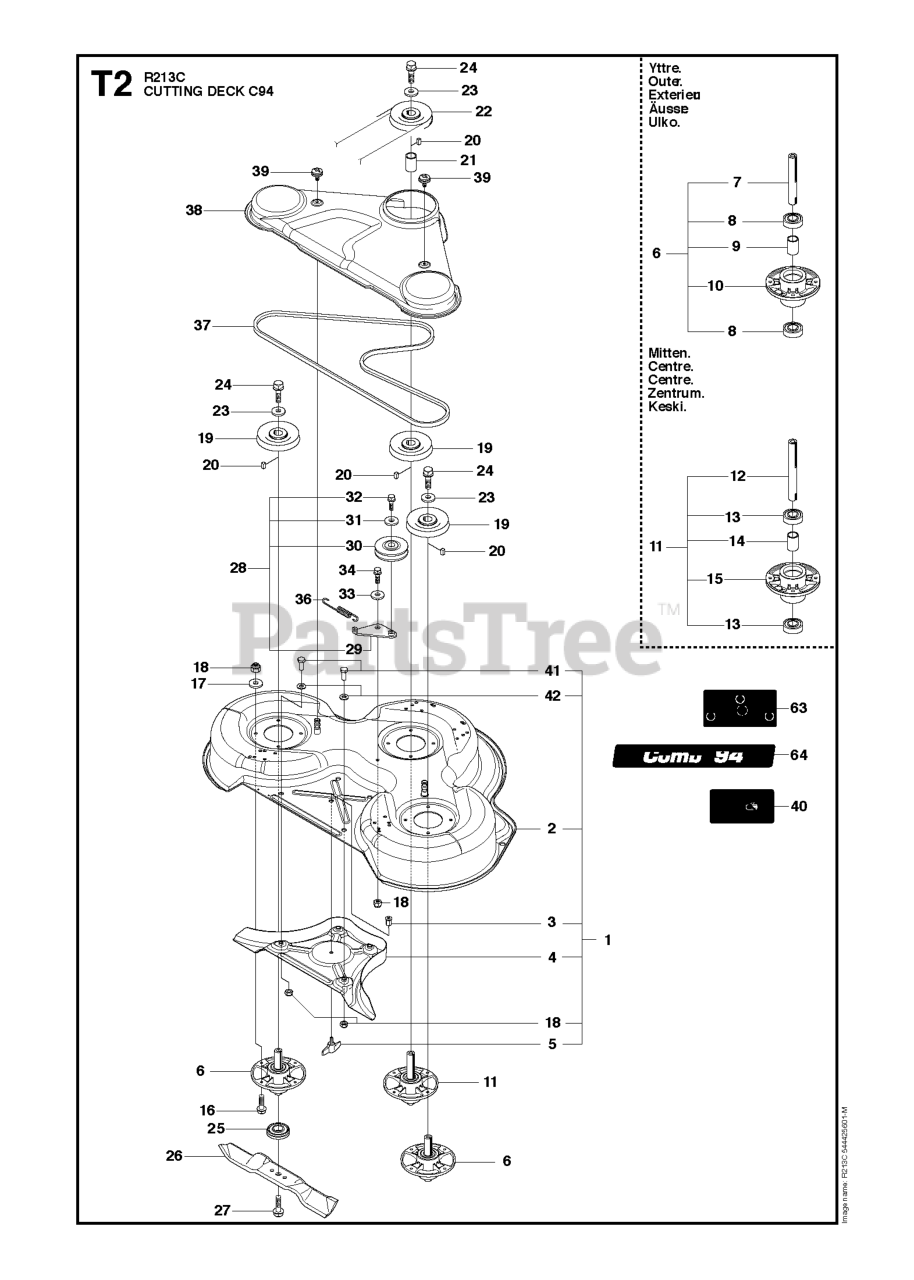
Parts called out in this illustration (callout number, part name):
4	PLUG C93 & C94
6	BLADE HOUSING ASSY
9	SPACING SLEEVE
10	BEARING HOUSING
14	SPACING SLEEVE
15	BEARING HOUSING
17	WASHER BRB 8.4X17
18	LOCKNUT M8
21	SPACING SLEEVE
25	BLADE BRACKET
30	PULLEY
33	WASHER
42	WASHER BRB 8.4X17
